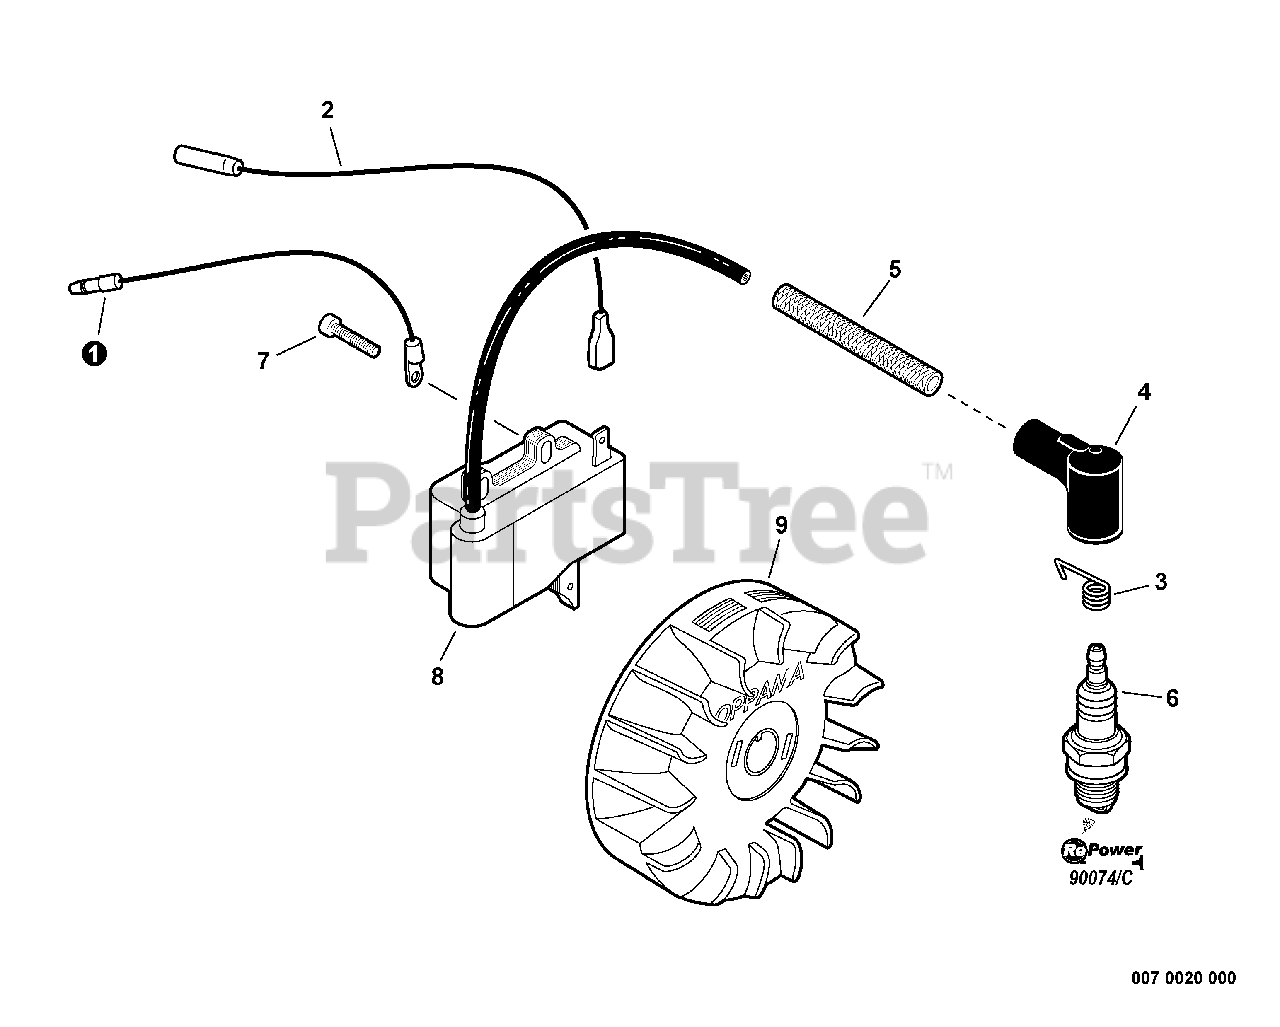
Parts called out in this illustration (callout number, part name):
1	LEAD
2	LEAD - IGNITION
3	TERMINAL, SPARK PLUG
4	CAP, SPARK PLUG
5	TUBE, INSULATOR
6	SPARK PLUG - BPMR8Y
6	SPARK PLUG - BPM8Y
7	BOLT 4×20
8	COIL, IGNITION
9	FLYWHEEL
10	TUNE-UP KIT - REPOWER
